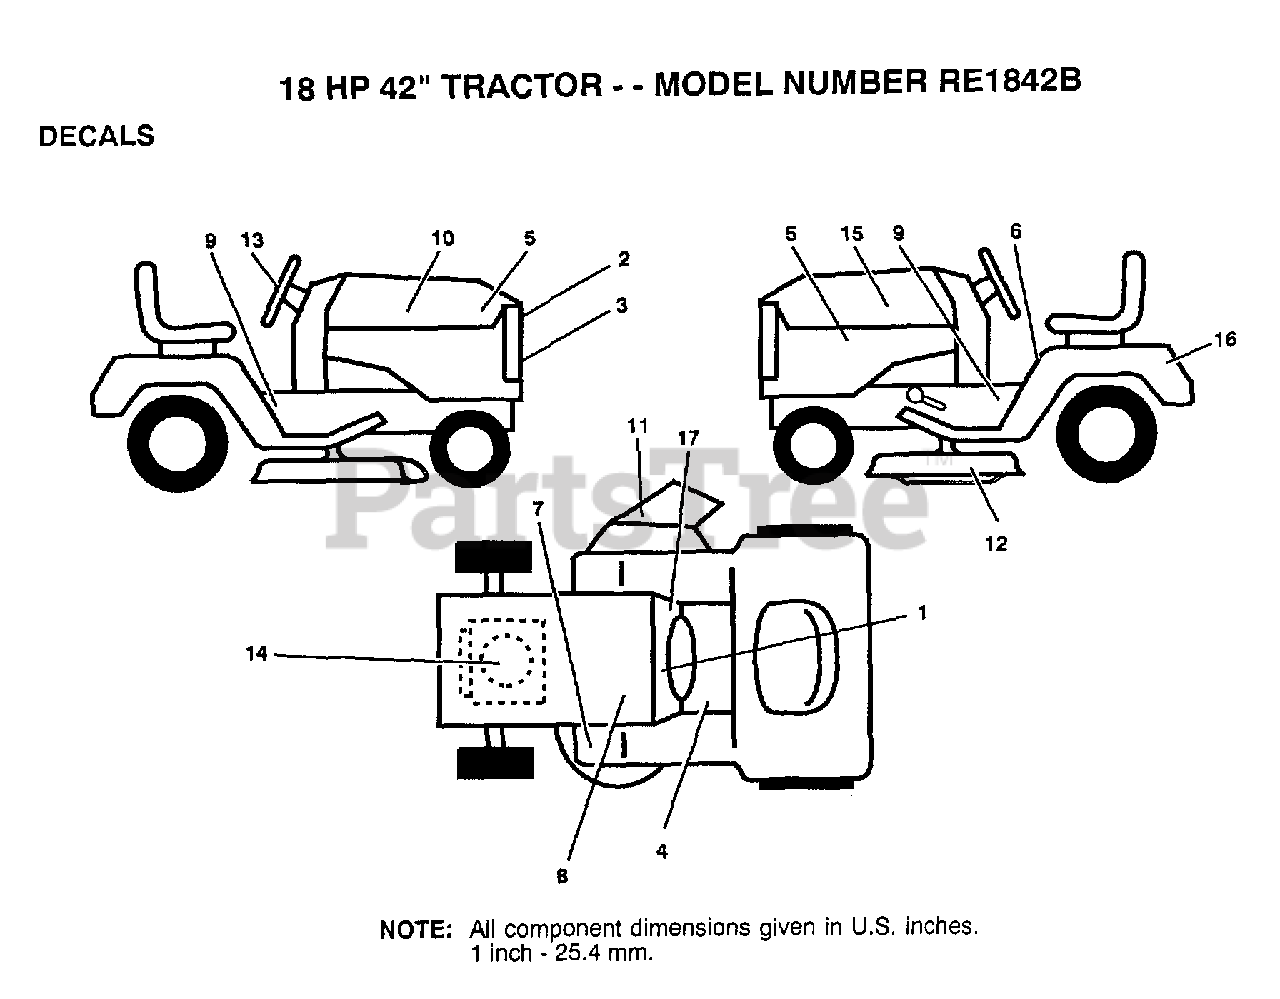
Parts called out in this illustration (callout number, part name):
3	GRILL DECAL
5	DECAL PANEL T
6	DECAL CAUTION
7	DECAL T
8	DECAL
9	CHASSIS DECAL
10	DECAL HOOD RH
11	DECAL WARNING
12	DECAL YT
13	"DECAL,STR WHL"
14	DECAL.ENG.272757
16	FENDER DECAL
